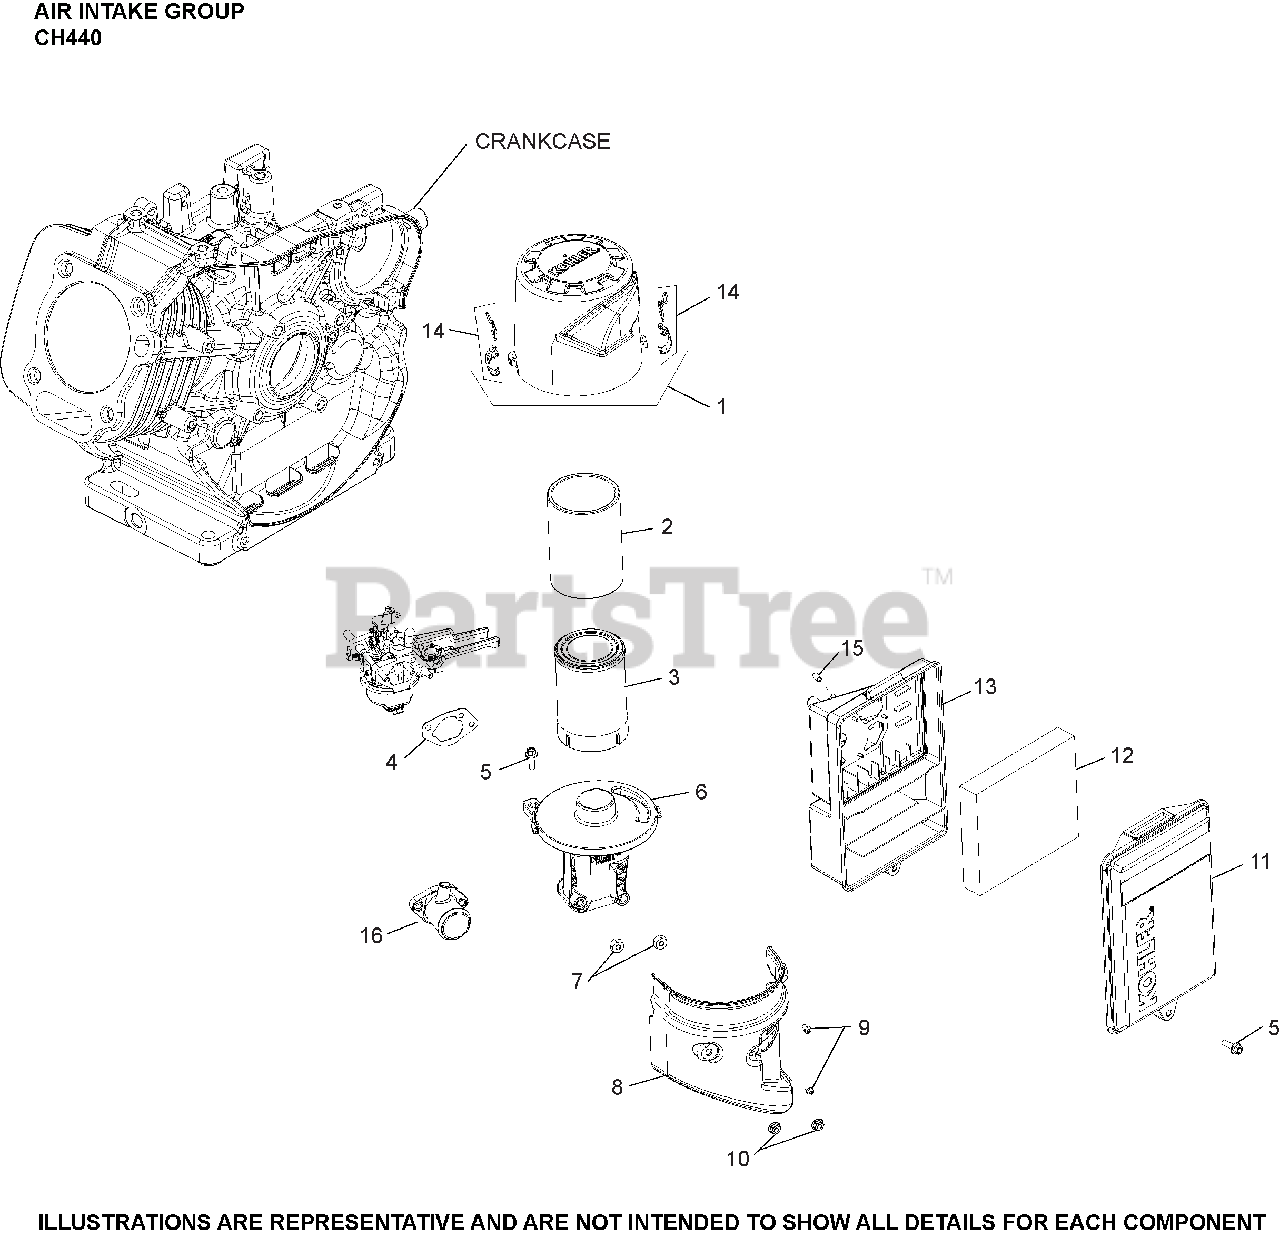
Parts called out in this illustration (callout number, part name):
1	COVER, AIR CLEANR ASSEMBLY
2	ELEMENT, PRE-CLEANER
3	ELEMENT, AIR FILTER - Also available Retail Packaged 17 883 03-S1Air Filter Kit
4	GASKET, AIR CLEANER
6	BASE ASSY,AIR CLEANER CYCLONIC
7	NUT, HEX (M6 THREAD, M8 BODY)
8	COVER, A/C/ BASE CH440
9	SCREW,COVR TO BLWR HOUSING
14	KIT, LATCH CLIP
